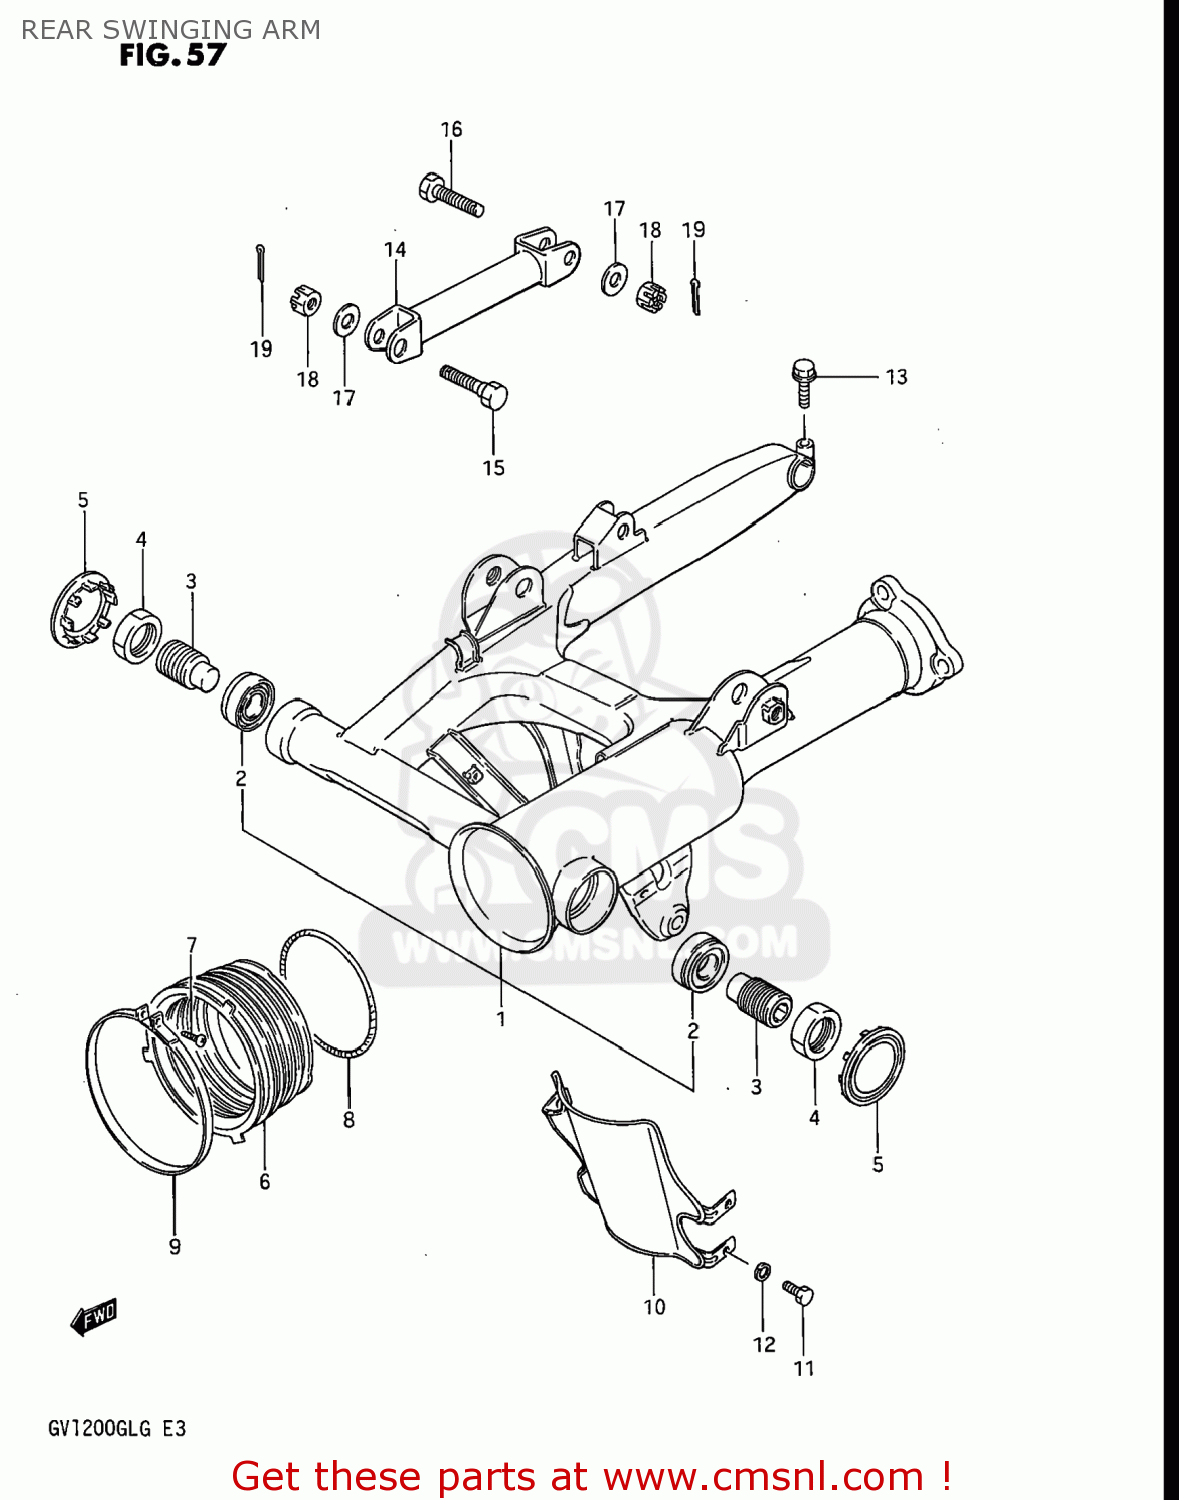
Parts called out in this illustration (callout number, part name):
1	ARM,REAR SWING
2	BEARING(17X40X13.25)
3	SHAFT,REAR SWING ARM
4	NUT
5	CAP,RR SWINGING ARM PIVOT NUT
6	BOOT,PROPELLER SHAFT
7	SCREW 4X25
8	SPRING,PROPELLER SHAFT
9	CLAMP
11	BOLT
12	WASHER,LOCK
13	BOLT
14	LINK,REAR TORQUE
15	BOLT
16	BOLT(10X39)
17	WASHER 10MM
18	NUT
19	PIN 20X20
